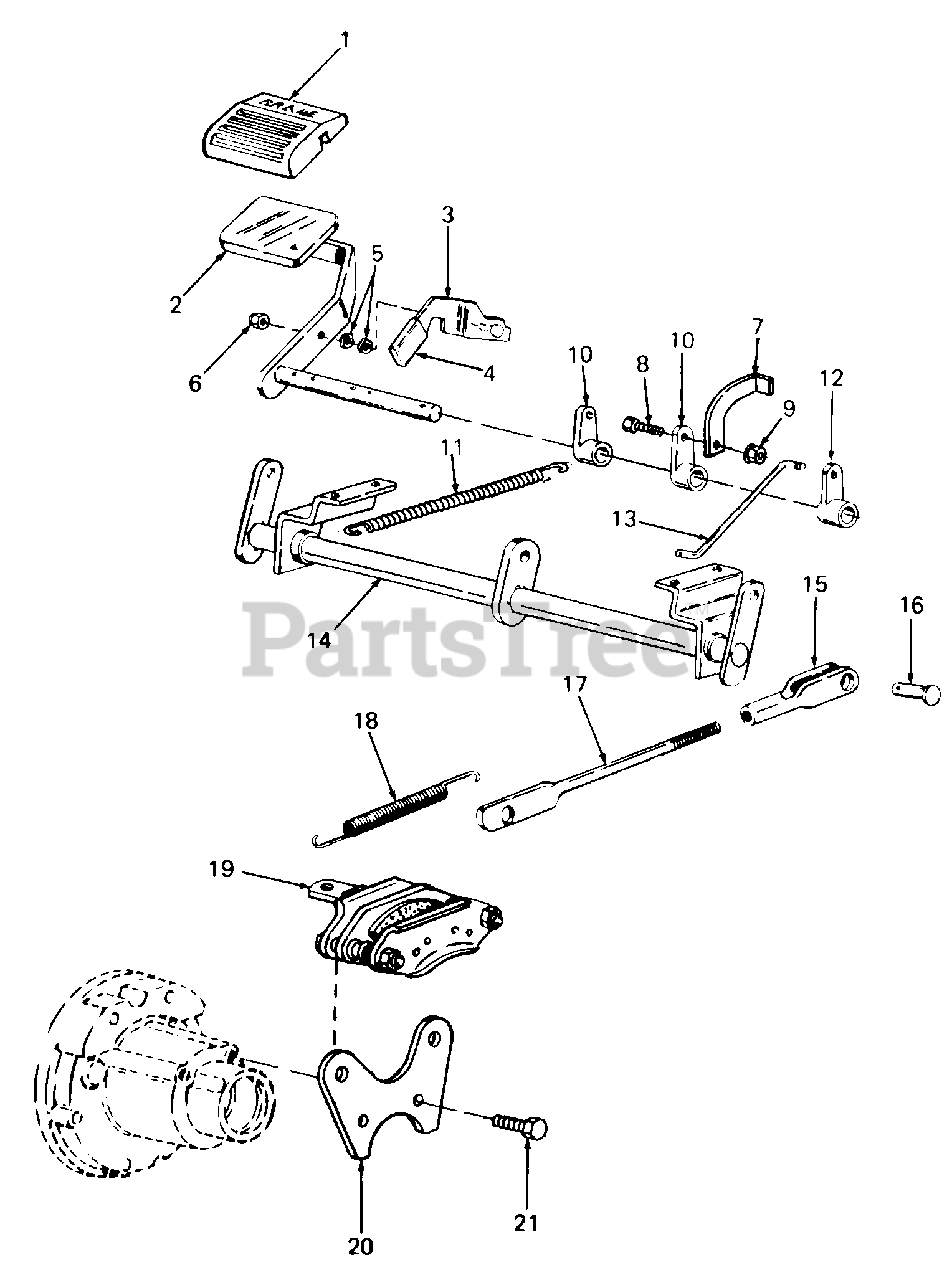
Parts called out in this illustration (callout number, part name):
1	Pad, Brake Pedal
2	Pedal Assy, Brake
5	Washer, Wave, 1/4 Dia
6	Nut, Hex Insert Lock, 1/4-20
8	Screw, Hex Cap, 3/8-16 X .75 Lg GR5
9	Nut, Hex Flanged Lock, 3/8-16 GR5
11	Spring, Return
15	Clevis, Adjustment
16	Pin, Clevis, 3/8 Dia X 1.0 Lg
17	Rod, Brake
18	Spring, Tension
19	Kit, Brake Caliper
20	Bracket, Brake Mounting
21	Screw, Hex Cap, 5/16-18 X 1.0 Lg GR5
